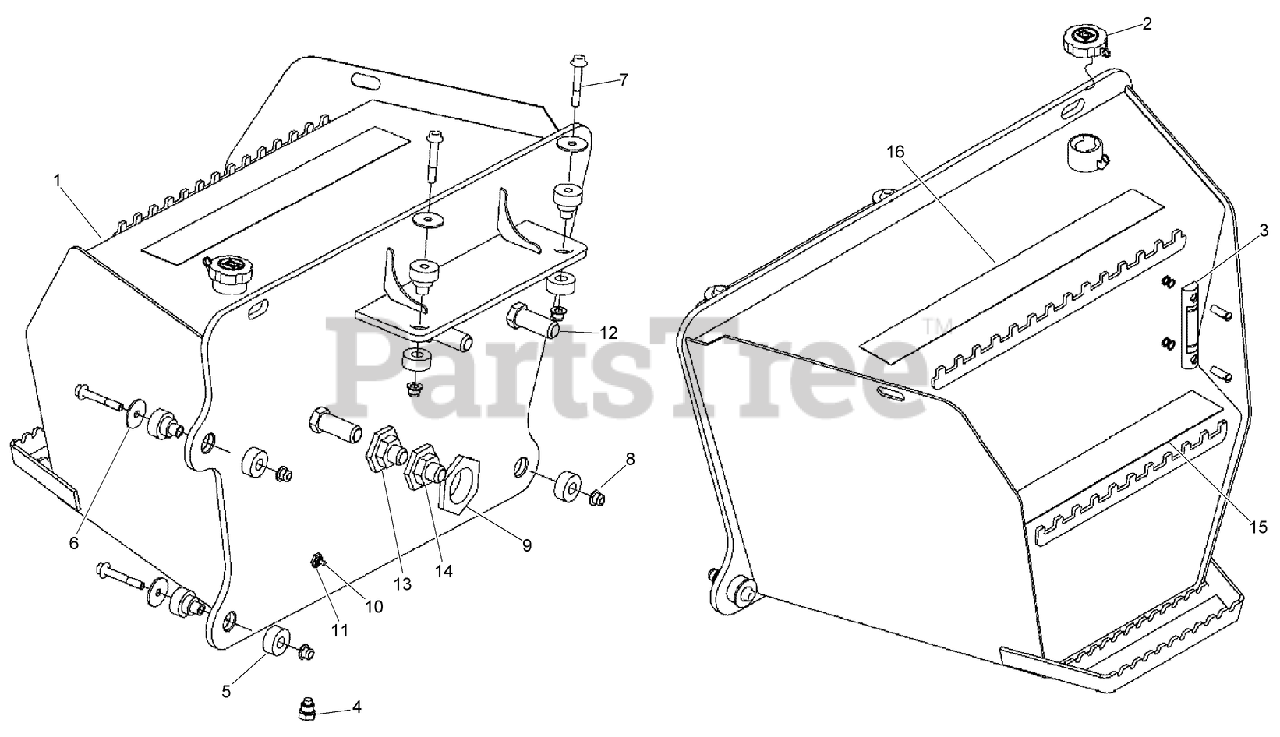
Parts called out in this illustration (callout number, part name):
1	WELDMENT - Hydraulic Tank
2	CAP-HYD FLUID (W/ LOCK)
3	GAUGE-SIGHT
4	PLUG-HEX, MAGNETIC
5	ISOLATOR-MOUNTING, UNIVERSAL
6	WASHER-FLAT
7	SCREW-HHF
8	NUT-HHF, LOCK
9	STRAINER-SUCTION
10	SENSOR-SENDER, OIL/WATER TEMP
12	CONNECTOR-Long Str Thkd 1.0, 37FL-ORB 1.0
13	STRAINER-MOUNTED, TANK
14	ADAPTER-STRAIGHT
15	TAPE-ANTI SKID, LOWER STEP
16	STRIP-ANTI SKID
